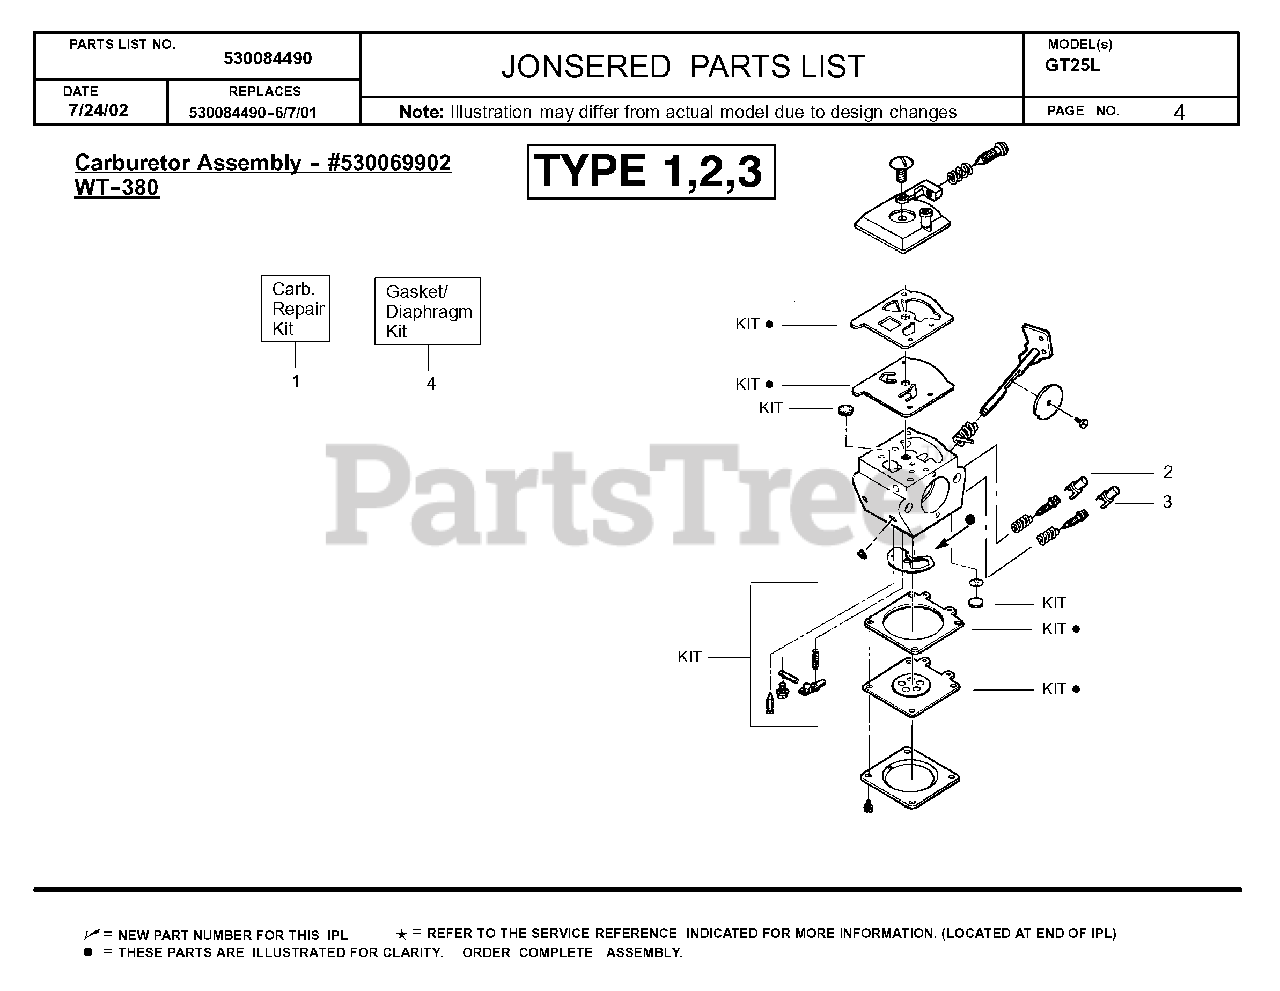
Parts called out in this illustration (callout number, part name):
1	CARB REPAIR KIT
2	LIMITER CAP-LOW
3	LIMITER CAP-HIGH
4	GASKET/DIAPHRAGM KIT
